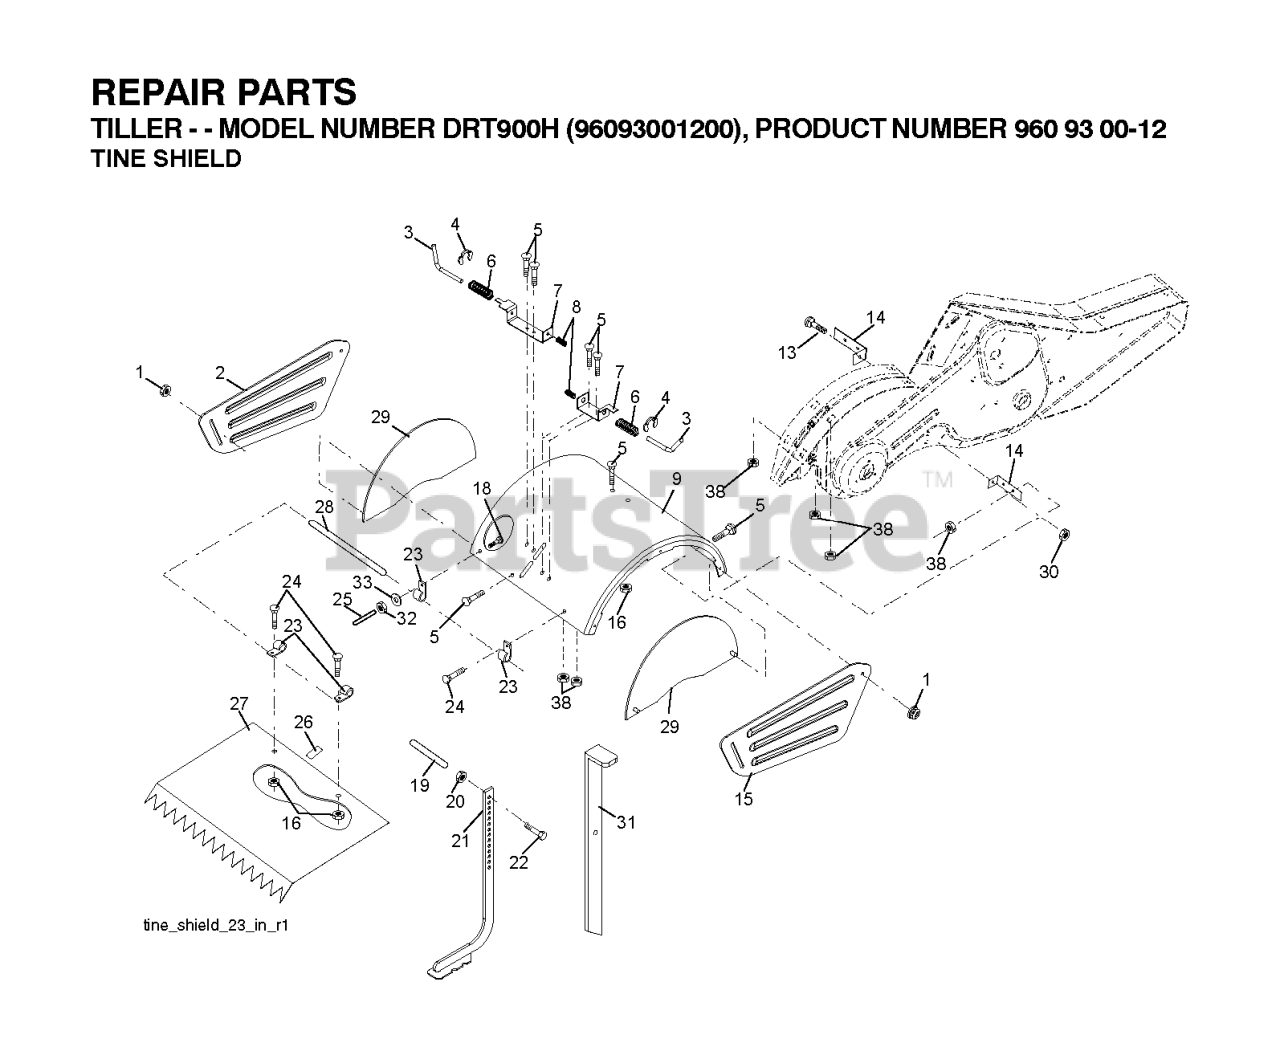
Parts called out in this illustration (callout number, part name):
1	NUT LOCK HEX FLANGE 5/16-18
2	SHIELD
3	STAKE PIN TI
4	RING, KLIP
5	BOLT, RDHD SQNK 5/16-18 X 3/4
7	BRACKET.LATCH.STAKE.3.20.BLACK
8	SPRING CRT
9	SHIELD.PNT.TINE.17"M
13	BOLT.CARRIAGE.5/16-18
14	BRACKET.TINE.SHIELD.TILLER
15	SIDE SHIELD RH
16	NUT T
20	NUT.HEX.3/8-16UNC
21	STAKE.DEPTH.16.CRT.BLACK
22	BOLT.375-16
25	VINYL CAP TI
26	PAD IDLER TI
27	SHIELD LEVELING
28	PIN.HINGE.TILLER
29	SHIELD.ASM.SIDE.ORANGE.(OLD)
30	LOCKNUT-FLANGE 5/16-18
31	RP.STAKE.DEPTH.DRAG.TILLR.GREY
32	NUT
33	LOCKWASHER
38	NUT
